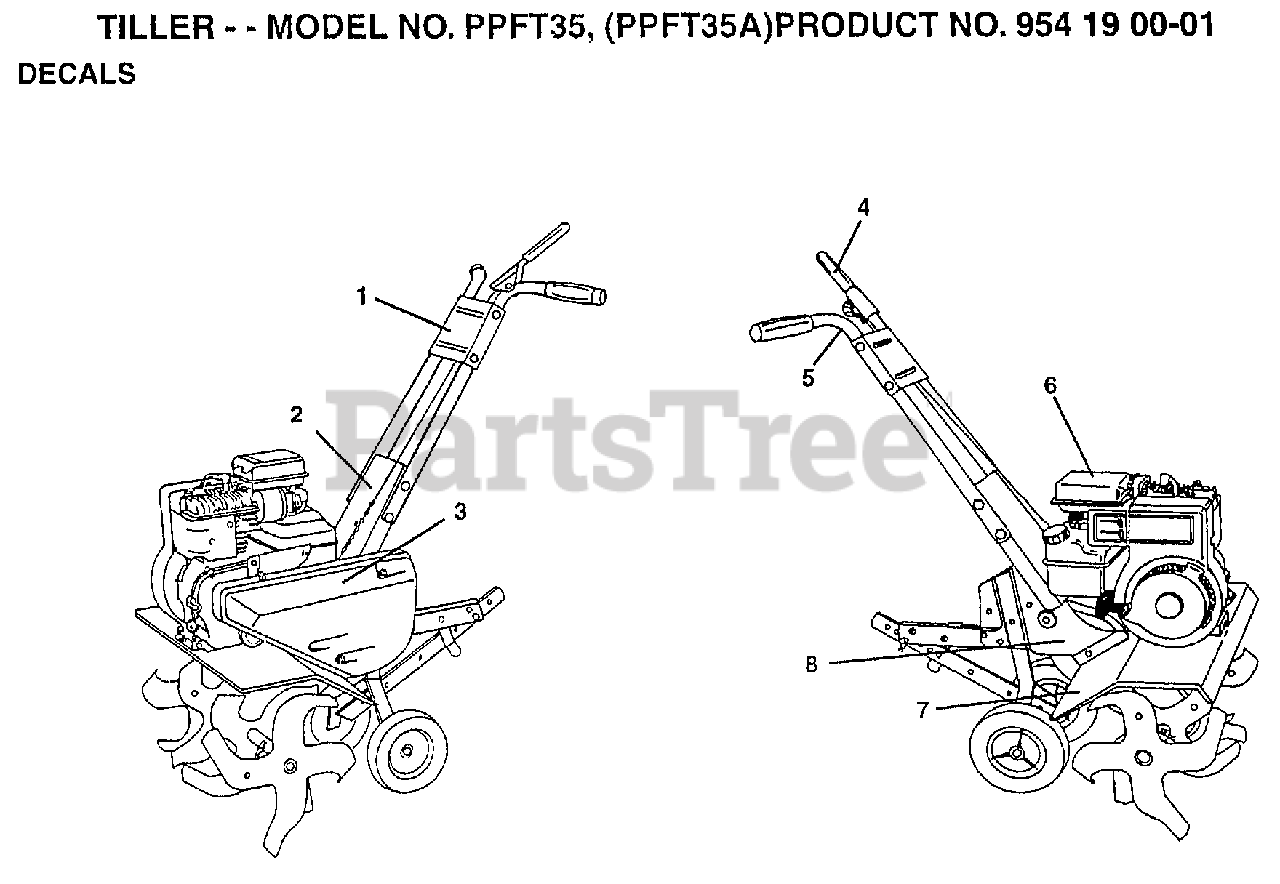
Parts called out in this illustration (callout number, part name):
1	"DECAL PANEL,CON,U"
2	"DECAL PANEL,CONT"
3	"DECAL GUARD,BELT"
8	DECAL.CUST.ASSIST
